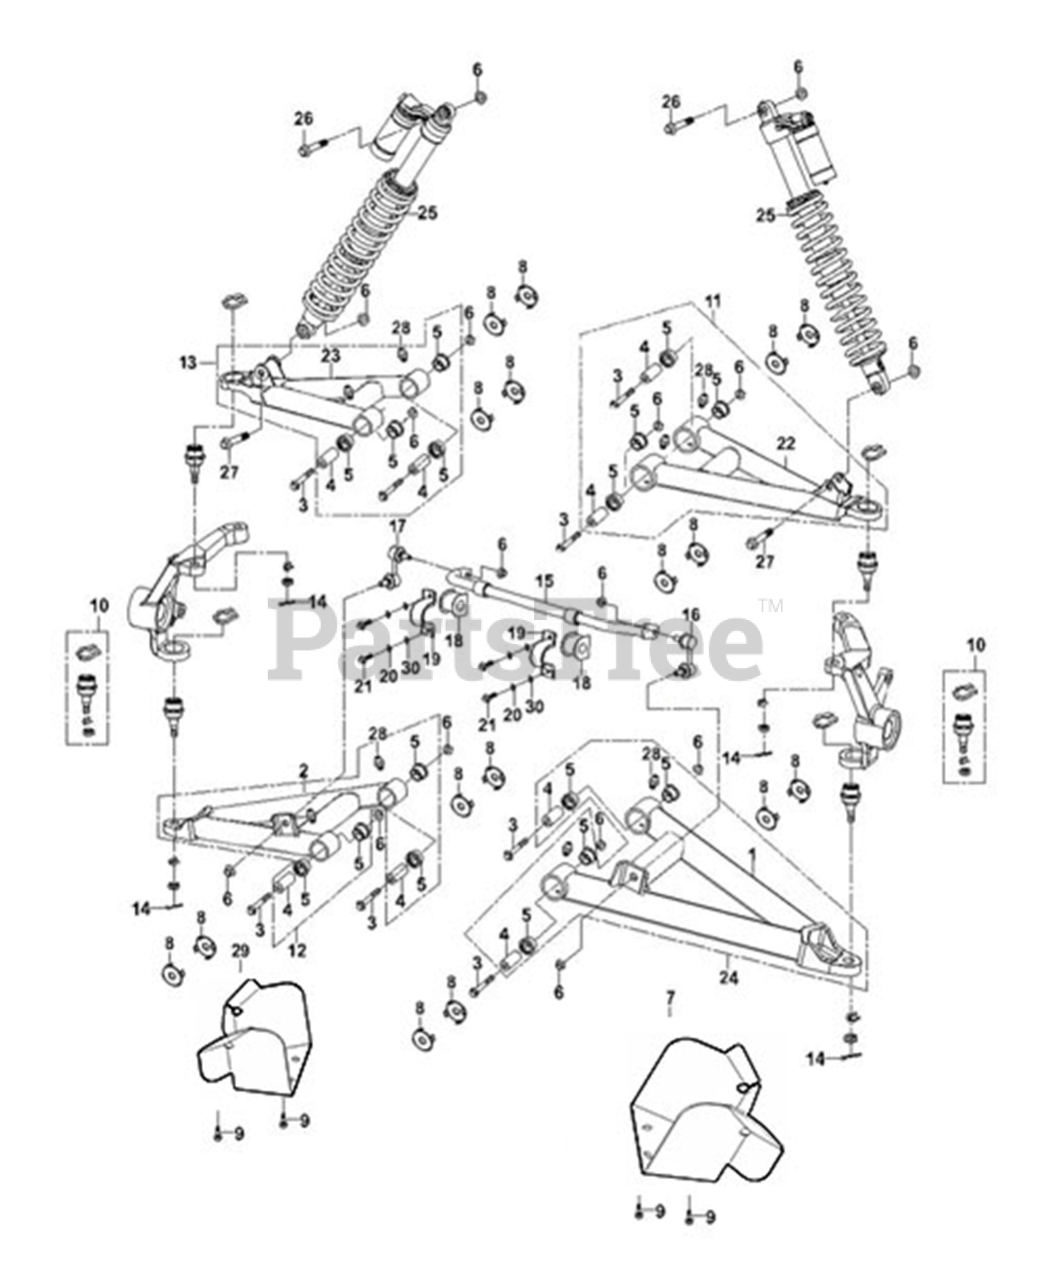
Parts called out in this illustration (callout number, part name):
1	Arm Welding Kit(Front Left Lower)
2	Arm Welding Kit(Front Right Lower)
3	HEX HEAD FLANGE BOLT M10X1.25-80
4	BUSHING 10.3X23X49.4
5	SHOULDER SPACER
6	LOCK NUT M10X1.25
7	CV SHIELD-FRONT (LH)
8	BUSHING CAP I
9	HEXAGON FLANGE BOLT M6X16
10	BALL JOINT KIT
11	UPPER A-ARM ASSEMBLY (FRONT LH)
12	LOWER ARM ASSEMBLY (FRONT RH)
13	UPPER A-ARM ASSEMBLY (FRONT RH)
14	COTTER PIN 2.5X30
15	STABILIZER BAR (FRONT)
16	ROD BALL KIT (RIGHT)
17	ROD BALL KIT (LEFT)
18	BUSHING - RUBBER U-TYPE
19	PRESS BLOCK REAR ANTI-ROLL BAR
20	SPRING WASHER
21	HEX FLANGE BOLT M10X1.25X20
22	Arm Welding Kit(Front Left Upper )
23	Arm Welding Kit(Front Right Upper)
24	LOWER ARM ASSEMBLY (FRONT LH)
25	FRONT SHOCK ABSORBER
26	HEX FLANGE BOLT M10X1.25X55
27	HEX FLANGE BOLT M10X1.25X60
28	SWING ARM NOZZLE
29	CV SHIELD-FRONT (RH)
